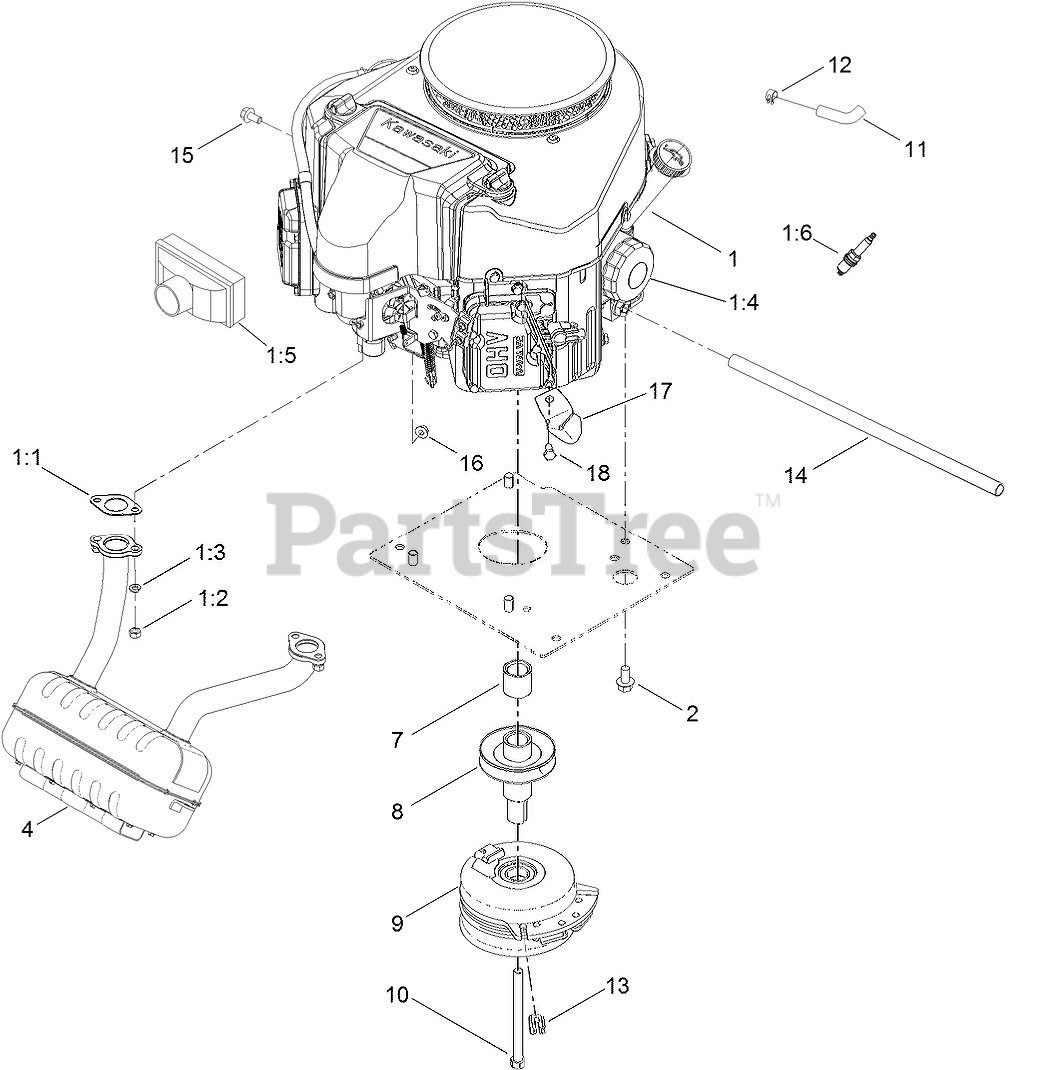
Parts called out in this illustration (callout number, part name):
1:1	GASKET-EXHAUST
1:3	WASHER-LOCK
1:4	FILTER-OIL
1:5	FILTER-AIR
1:6	SPARK PLUG
2	SCREW-HHF
4	MUFFLER-TWIN, KAWASAKI
7	SPACER
8	PULLEY-ENGINE
9	CLUTCH-ELECTRIC
10	SCREW-HH
11	HOSE-FUEL
12	CLAMP-HOSE
13	ISOLATOR-CLUTCH
14	TUBE-DRAIN, OIL
15	SCREW-HHF
16	NUT-HF
17	SHIELD-SPARK
18	SCREW-HH
